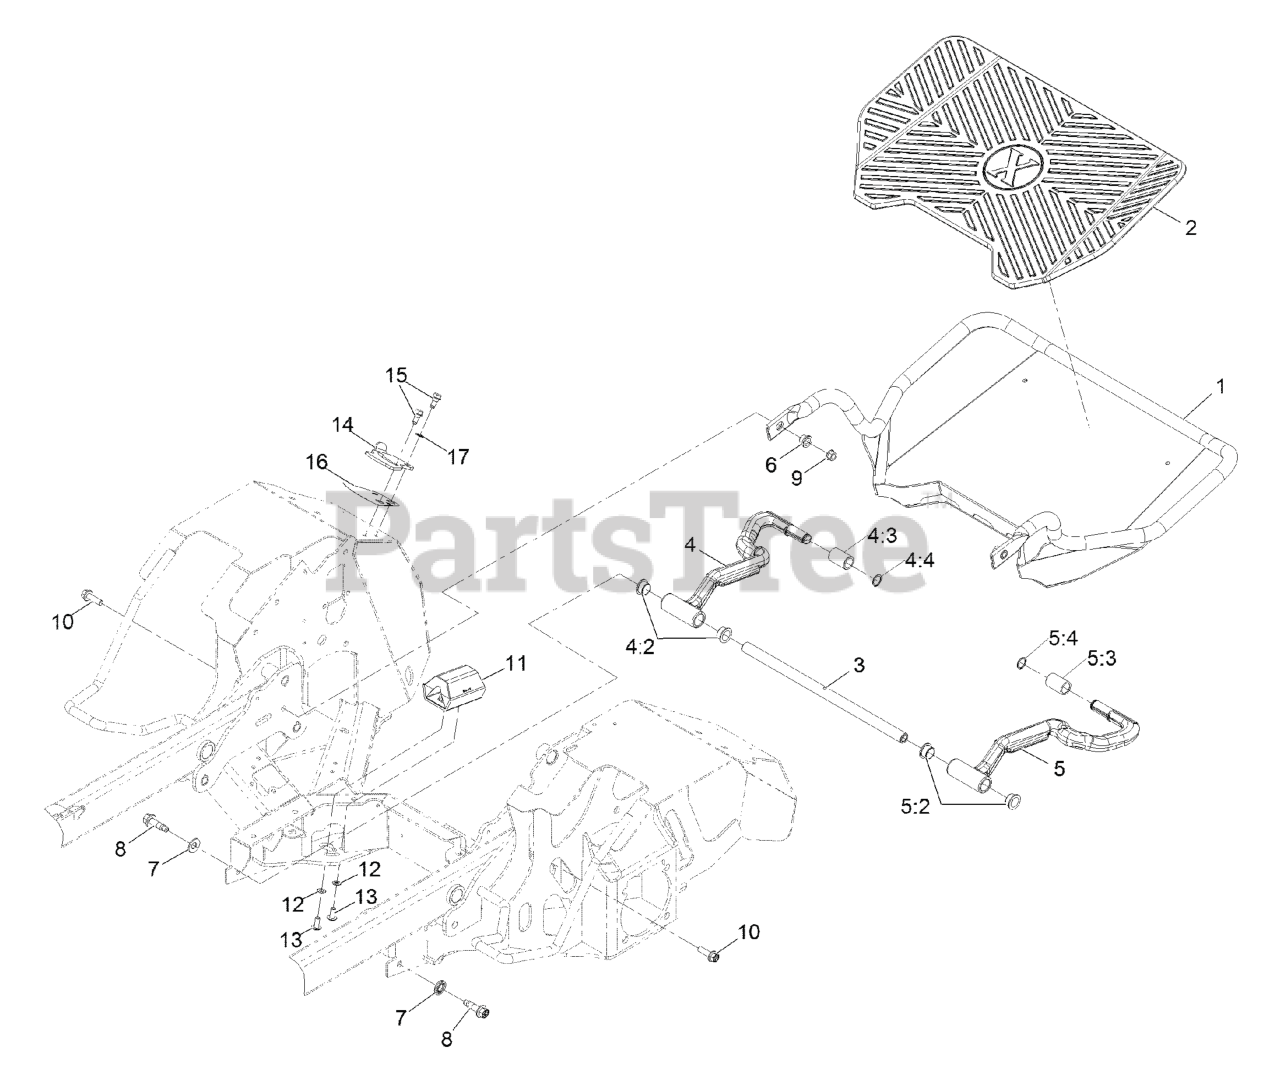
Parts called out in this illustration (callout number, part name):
1	WELD, PLATFORM
2	MAT, PLATFORM
3	SHAFT, CROSS
4	ASM, RT ARM W/ BUSHINGS
4:2	BUSHING-FLANGE
4:3	Bushing, Sleeve
4:4	RING-SNAP
5	ASM, LT ARM W/ BUSHINGS
5:2	BUSHING-FLANGE
5:3	Bushing, Sleeve
5:4	RING-SNAP
6	BUSHING-FLANGED
7	WASHER-SPRING
8	SCREW-HHF
10	SCREW, HHF
12	WASHER-LOCK
13	SCREW-TORX
14	LATCH, PLATFORM
15	SCREW-SHOULDER
16	DECAL-LATCH LOCK
17	WASHER, PLASTIC
